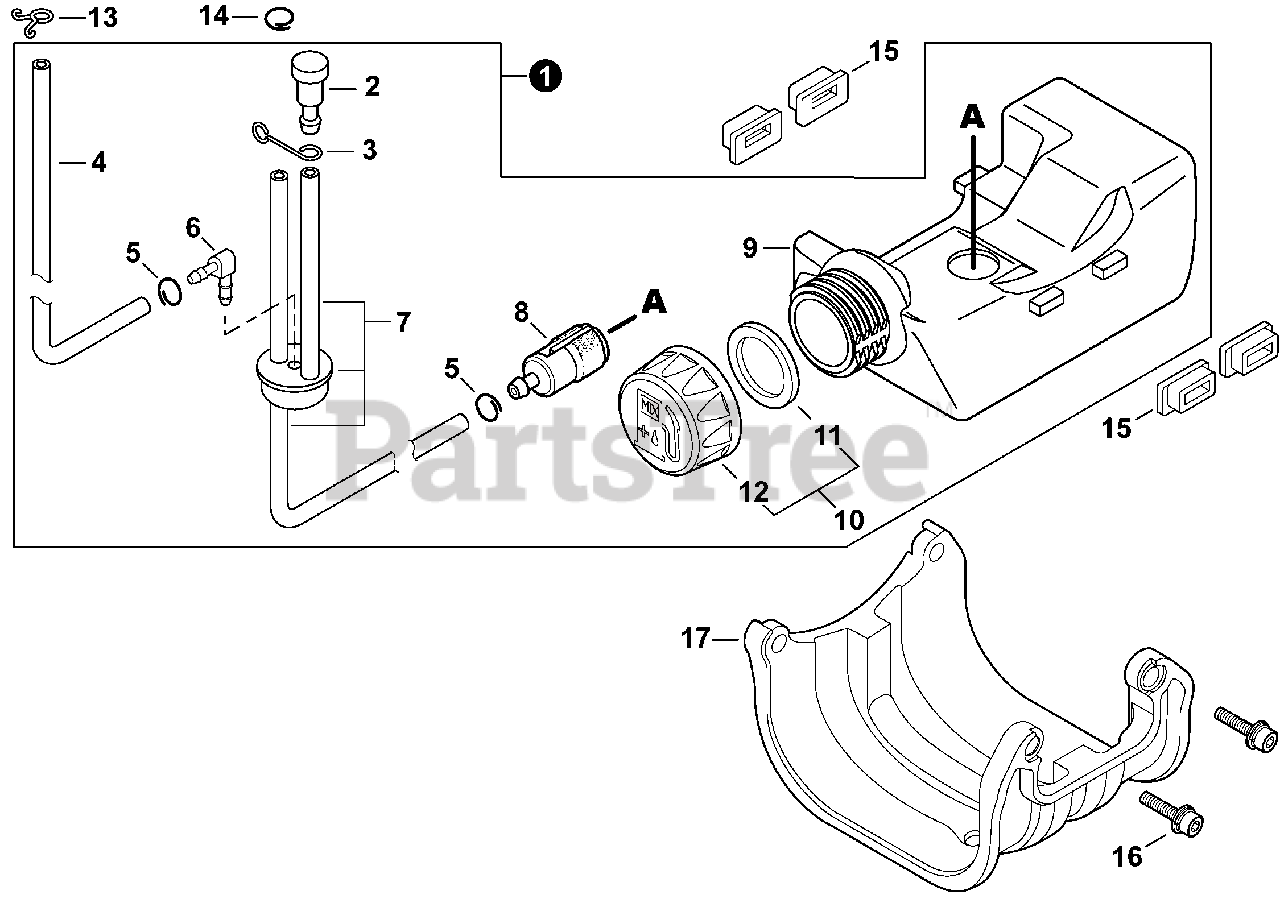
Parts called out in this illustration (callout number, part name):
1	TANK ASSY, FUEL
2	VENT ASSY
3	CLIP, VENT ASSY
4	PIPE, FUEL RETURN
6	CONNECTOR, PIPE
7	PIPE, FUEL
8	FILTER, FUEL 125-528
9	TANK, FUEL
10	CAP ASSY, FUEL
11	GASKET, FUEL CAP
12	CAP ASSY, FUEL
13	CLIP, SPRING 5.2
15	CUSHION, FUEL TANK
16	BOLT 5x16
17	GUARD, PLASTIC FUEL TANK
